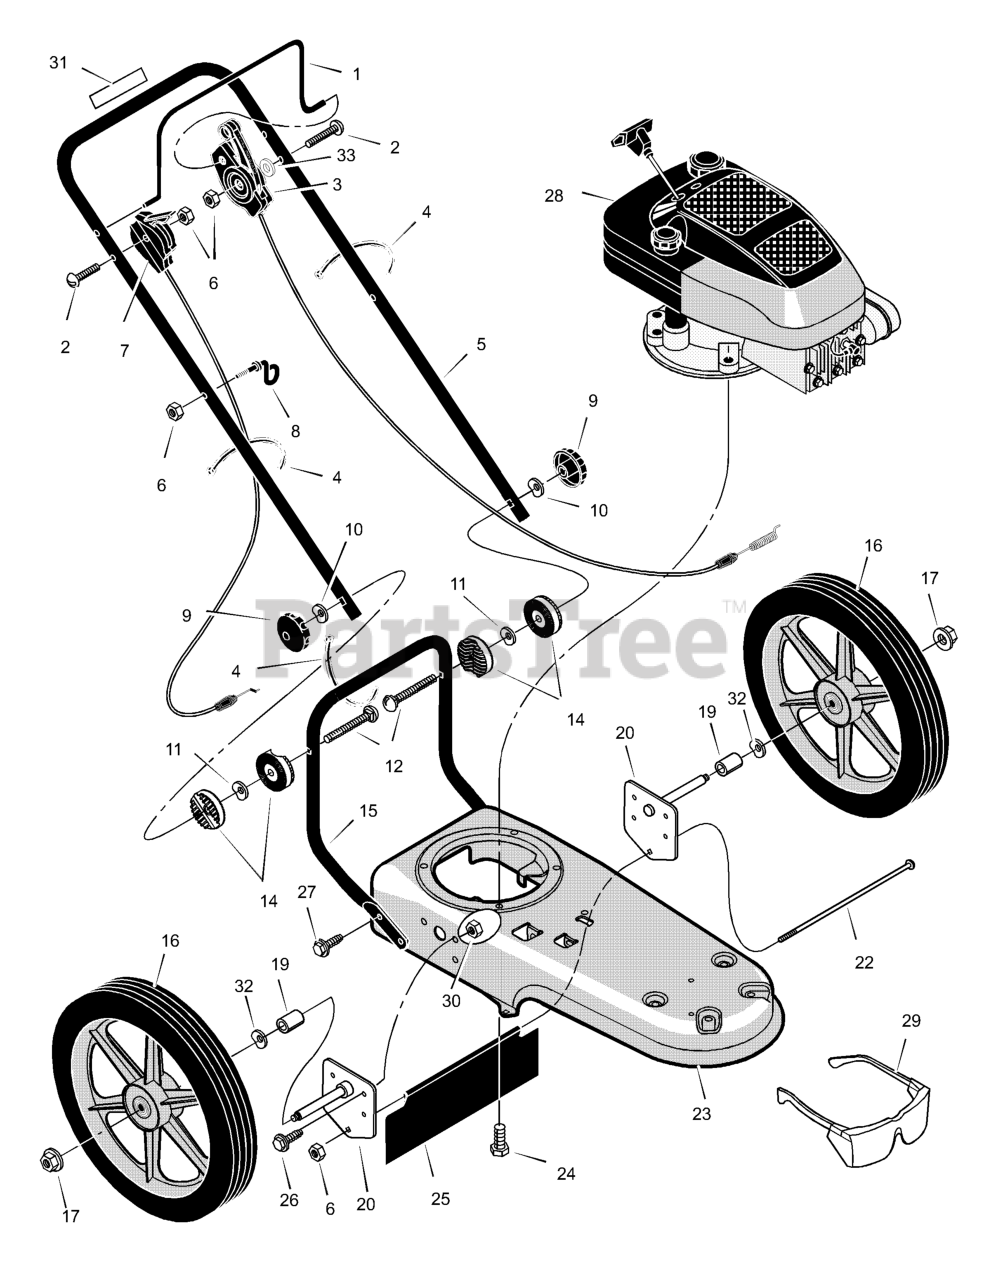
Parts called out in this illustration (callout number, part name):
1	LEVER, Stop
3	CABLE, Control Latching
4	TIE, Cable
5	HANDLEBAR
7	CONTROL, Throttle
8	GUIDE, Rope
9	KNOB, Handlebar
11	WASHER, Spring
14	PIVOT, Handlebar
15	HANDLEBAR, Lower
16	WHEEL & TIRE
17	NUT, Axle
18	WASHER
20	ASSEMBLY, Axle & Bracket
22	BOLT, Carriage
25	SHIELD, Trailing
28	Engine
29	PROTECTION, Eye
31	DECAL, Engine Stop
32	WASHER, Spring
33	SPACER, PM .26x.5x.2
